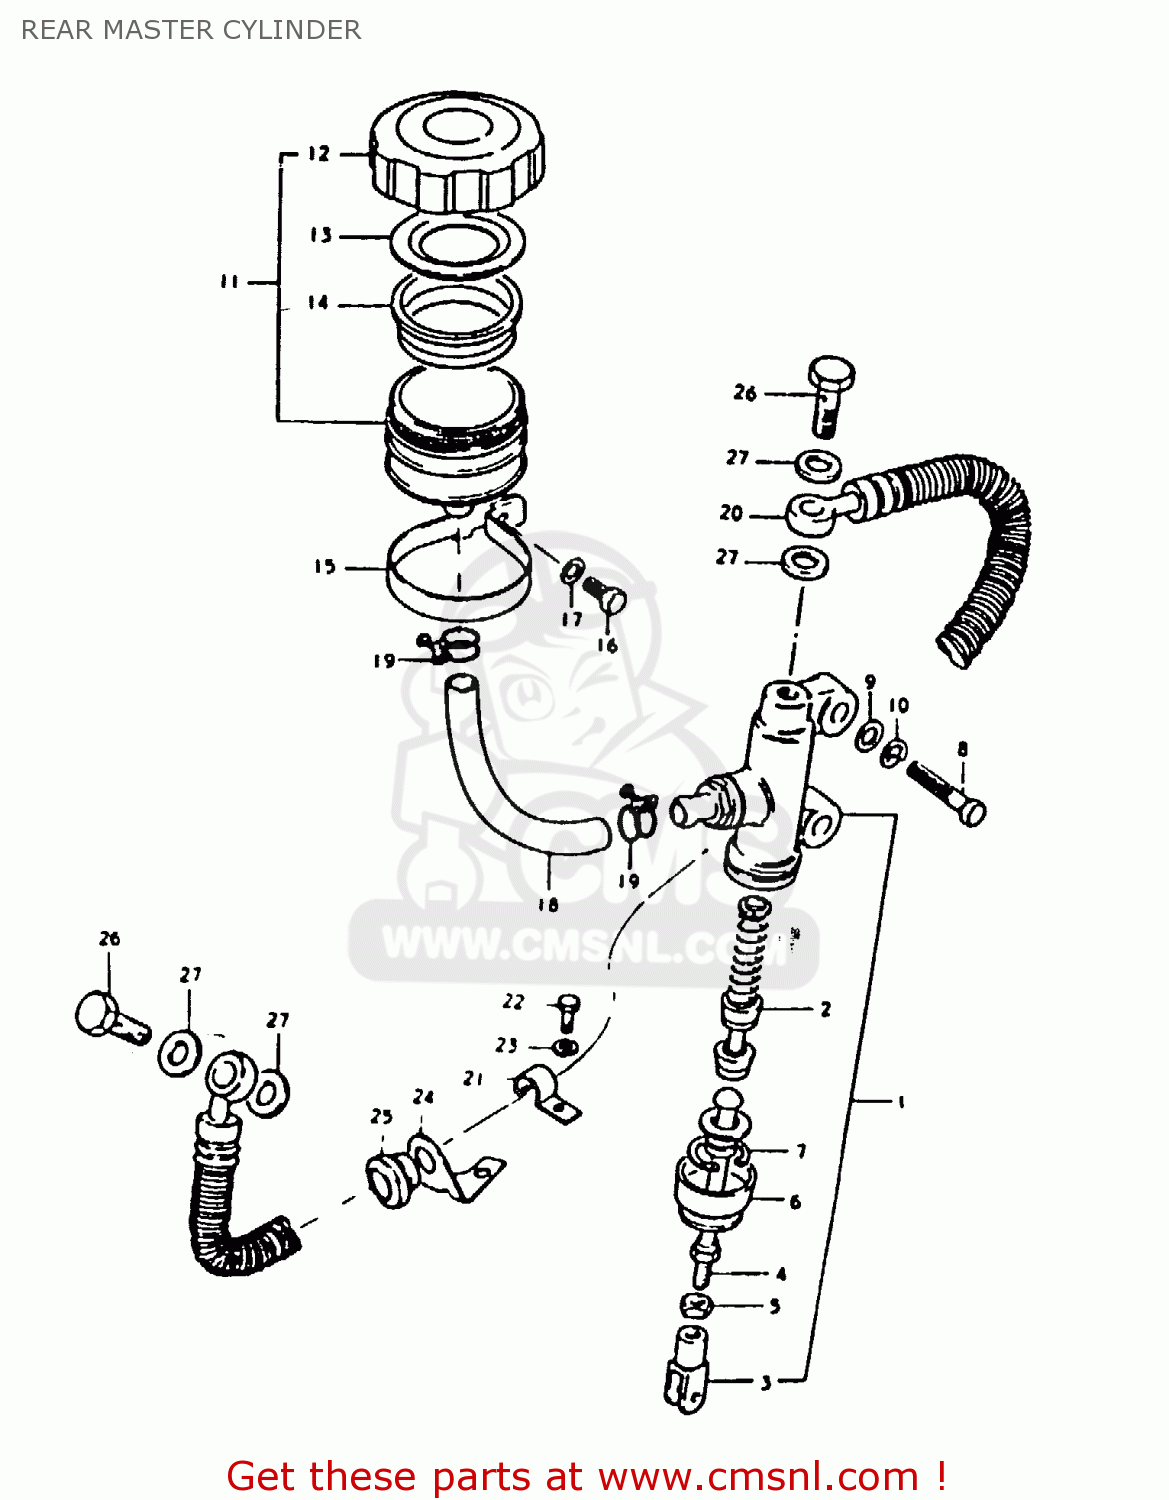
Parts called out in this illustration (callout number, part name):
1	CYLINDER ASSEMBLY,REAR MASTER
2	PISTON/CUP SET
3	YOKE
4	ROD,PUSH
5	NUT
6	BOOT
7	CIRCLIP
8	BOLT (8X30)
9	WASHER
10	LOCK WASHER
11	TANK ASSEMBLY,RESERVOIR
12	CAP
13	PLATE,DIAPHRAGM
14	DIAPHRAGM
15	CLAMP
16	BOLT, UPPER
17	LOCK WASHER
18	HOSE,RESERVOIR TANK
19	CLAMP
20	HOSE,REAR BRAKE
21	CLAMP,REAR BRAKE HOSE
22	SCREW(6X8)
23	LOCK WASHER
24	GUIDE,BRAKE HOSE
25	GROMMET,BRAKE HOSE GUIDE
26	BOLT UNION
27	WASHER
